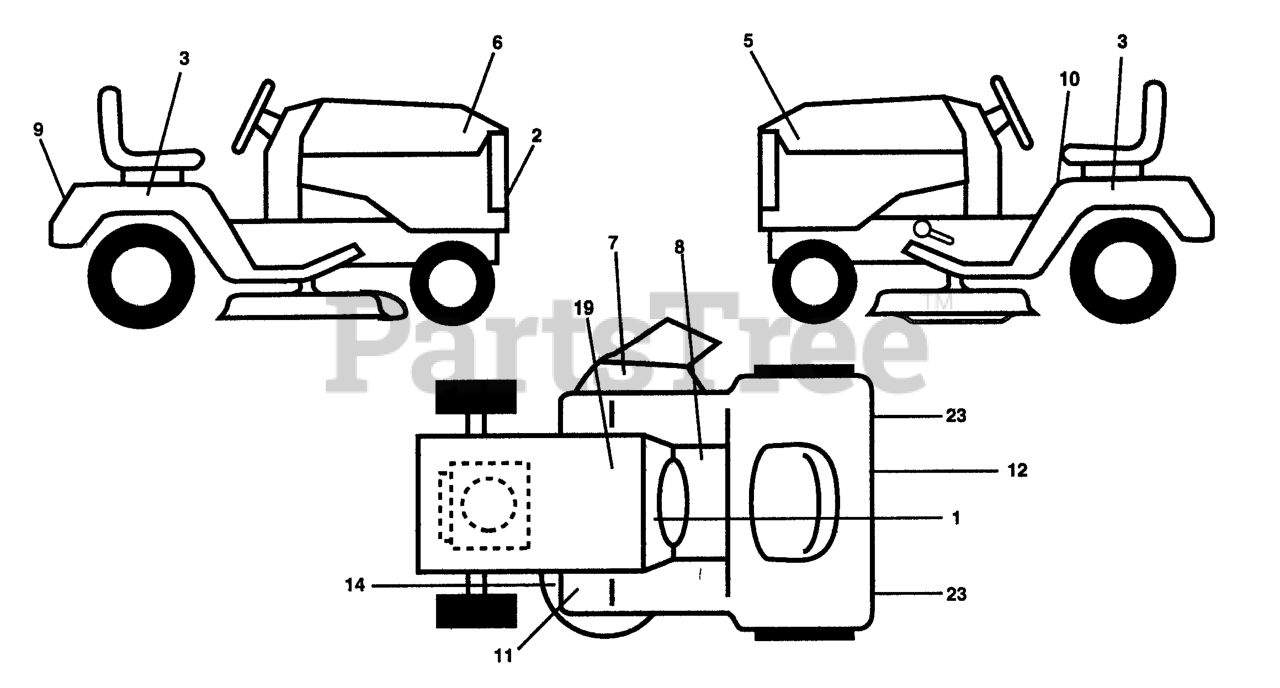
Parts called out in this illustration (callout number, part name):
1	DECAL, OPERATING INSTRUCTIONS
2	DECAL.GRILLE.HUSQ
3	DECAL, FENDER
5	DECAL, HOOD LH GTH220 HYDRO
6	DECAL HOOD RH GTH220 HYDRO
7	DECAL WARNING (ENGLISH/FRENCH)
8	DECAL PARK BRAKE
9	DECAL FENDER HUSQ
10	DECAL FENDER DANGER
12	DECAL D-BAR
19	DECAL BTRY SYMBOLS
23	REFLECTOR-TAIL YT
